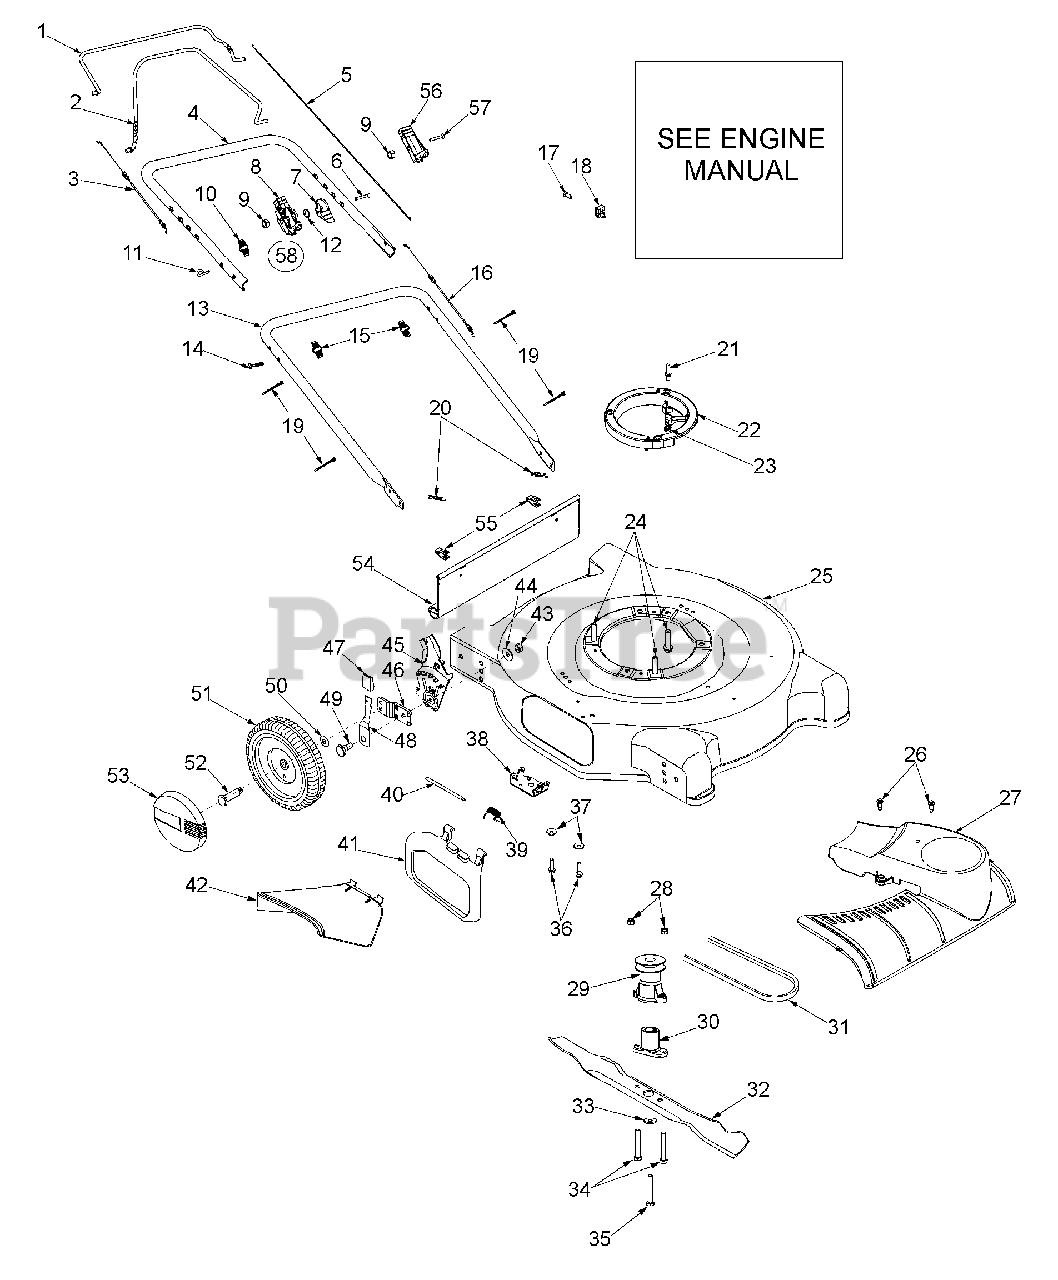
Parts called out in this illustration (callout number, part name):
6	Screw Oval C-Sunk 1/4-20 x 1.81
7	Throttle Lever
8	Throttle Housing
9	Hex Lock Nut 1/4-20
11	Eye Bolt 1/4-20
12	Curved Washer .663 x .980 x .014
14	Carriage Bolt 5/16-18 x 2.0
15	Knob
16	Throttle Cable: 51" B&S
17	Hex Screw: T: #10-32 x .625 B&S
18	Cable Clamp B&S
19	Tie Cable
20	Cotter Pin
21	Pin-Belt Keeper
22	Engine Spacer
23	Hex Nut 1/4-20 Thread
24	Tapp Screw w/Hex Lock Wash
25	Deck 22" SD
26	Screw #12 x .457
27	Trans Cover - Black w/Logo
28	Hex Lock Nut 1/4-20 Thd.
29	Drive Pulley
30	Blade Adapter Kit
31	V-Belt
32	Blade 22"
33	Bell Washer .396 I.D. x 1.140 O.D. x .095
34	Hex Screw 1/4-20 x 1.50
35	Hex Screw 3/8-24 x 2.50
36	Tapp Screw 1/4-20 x .500
37	Bell Wash .265 x .75 x .062
39	Torsion Spring
40	Hinge Pin
41	Mulch Plug
42	Chute Deflector
43	Hex Nut 3/8-16
44	Bell Washer .39 ID x 1.38 OD
47	Knob
48	Height Lever
49	Shldr Screw .500 Dia x .434
50	Bell Washer .380 x .880 x .062
51	Wheel 8 x 1.75 Disk Bar Gray
52	Shoulder Screw .498 x 1.445
53	Hubcap: Euro: Grey
54	Rear Flap
55	Clip
56	Throttle Housing
57	Oval C-Sunk Screw 1/4-20 x 1.31
58	Throttle Comp.
